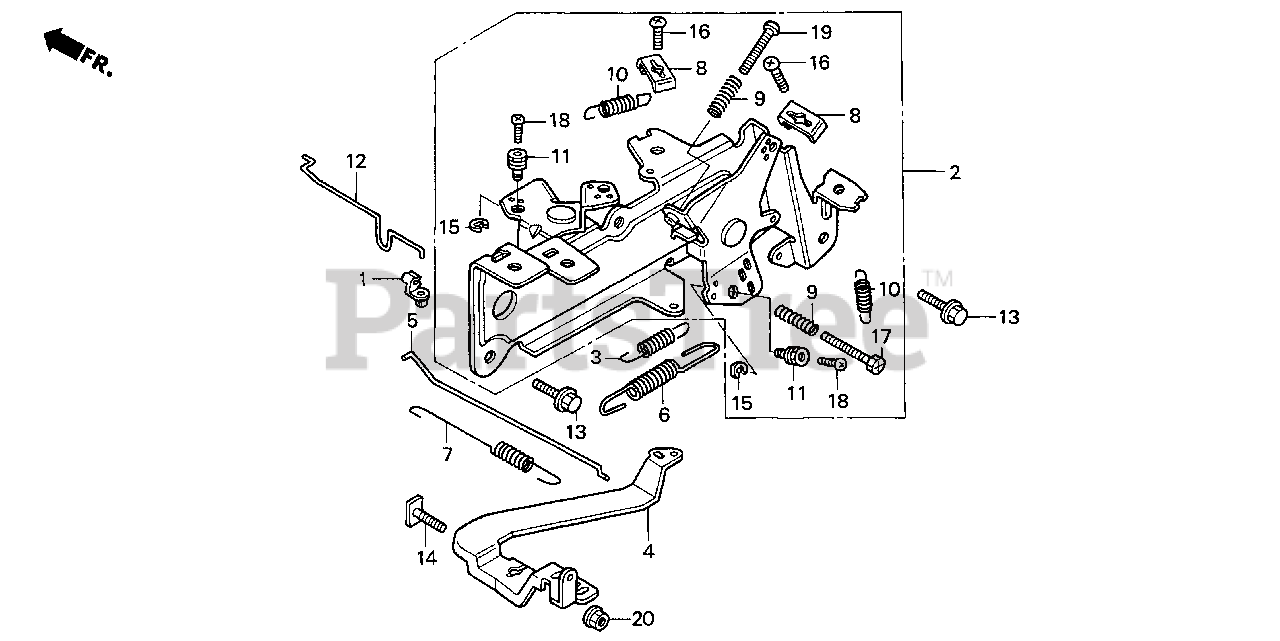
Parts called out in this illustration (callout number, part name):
1	JOINT, ROD
2	CONTROL ASSY.
3	SPRING, STARTER
4	ARM, GOVERNOR
5	ROD, GOVERNOR
6	SPRING, GOVERNOR
7	SPRING, THROTTLE RETURN
8	HOLDER, CABLE
9	SPRING, CONTROL ADJUSTING
10	SPRING, CABLE RETURN
11	HOLDER, WIRE
11	HOLDER, CABLE
12	ROD, CHOKE CONTROL
13	BOLT, FLANGE (6X14)
14	BOLT, GOVERNOR ARM
15	CIRCLIP (5MM)
16	BOLT, SLOT (5X16)
17	BOLT, SLOT (5X25)
18	BOLT, RECESSED (4X6)
19	SCREW, PAN (5X25)
20	NUT, FLANGE (6MM)
